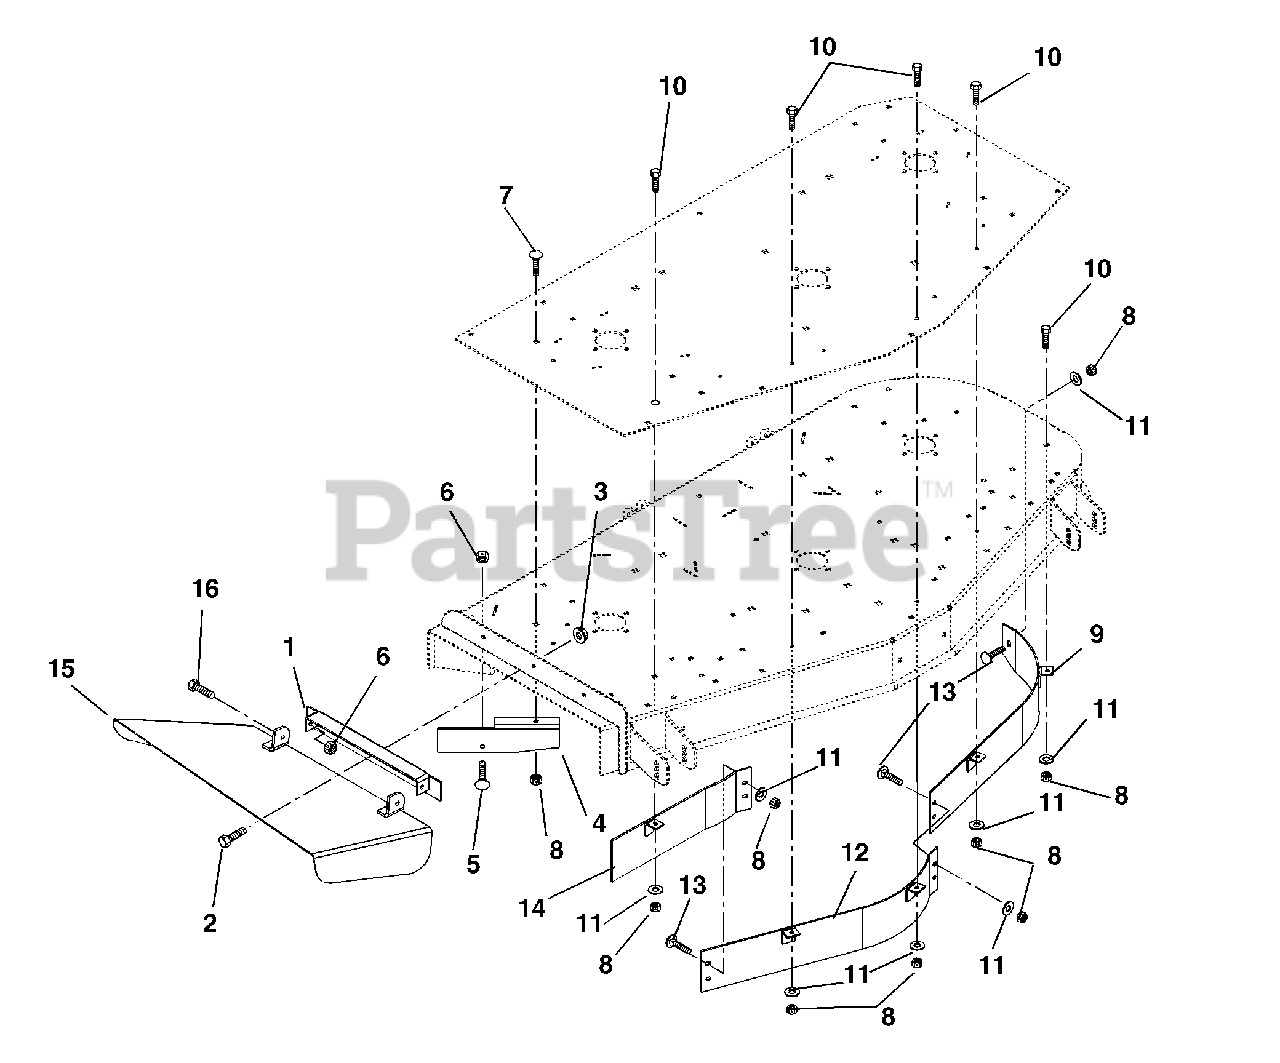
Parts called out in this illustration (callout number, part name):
1	Weldment, Discharge Chute Bracket
2	Bolt-Hex .38-16 x 1.00 Grade 5
3	Nut-Locking-Flange .38-16
4	Deflector, 60
5	Bolt-Round Head Square Neck .38-16 x 1.00 Grade 2
6	Nut-Locking-Center .38-16
7	Bolt-Round Head Square Neck .31-18 x 1.00 Grade 5
8	Nut-Locking-Nylon .31-18
9	Weldment, 60" Left Hand Baffle-Upper
10	Bolt-Hex .31-18 x 1.00 Grade 5
11	Washer-Flat-Steel .312 x .734 x .065
12	Weldment, 60" Center Baffle-Up
13	Bolt-Round Head Square Neck .31-18 x .75 Grade 5
14	Weldment, 60" Right Hand Baffle-Upper
15	Weldment, Discharge Chute 60"
16	Bolt-Hex .38-16 x 1.00 Grade 5
17	60" Discharge Cover
18	60" Mulch Kit
